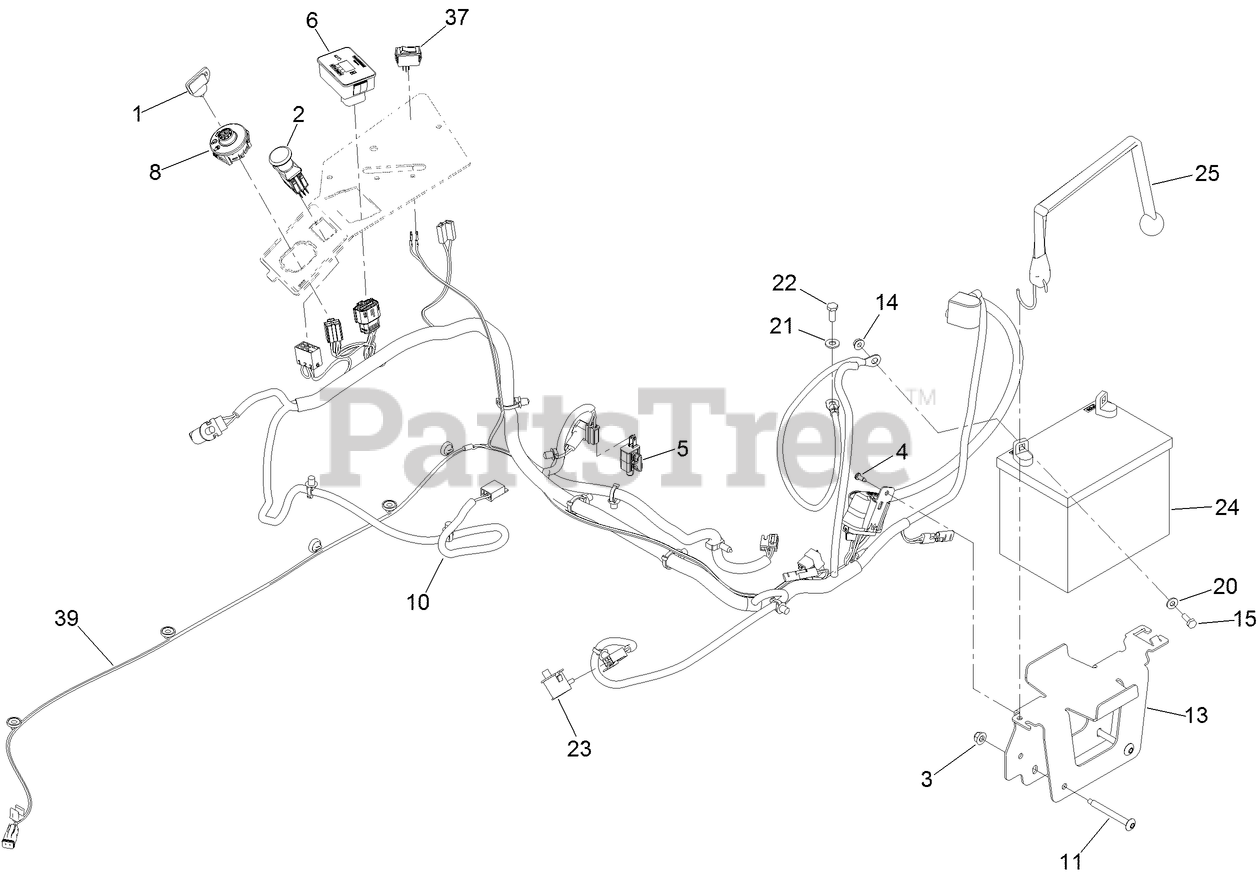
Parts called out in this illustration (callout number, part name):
1	KEY-IGNITION
2	SWITCH-PTO
3	NUT-HF, NI
4	SCREW-FORMING, THREAD
5	SWITCH
6	MODULE ASM
8	SWITCH-IGNITION
10	HARNESS-WIRE
11	SCREW-TORX
13	TRAY-BATTERY
14	NUT-HF
15	SCREW-HH
20	WASHER-FLAT
21	WASHER-PLAIN
22	SCREW-HH
23	SWITCH-BAIL
24	BATTERY
25	STRAP-BUNGEE
37	SWITCH-ROCKER
39	HARNESS - WIRE
